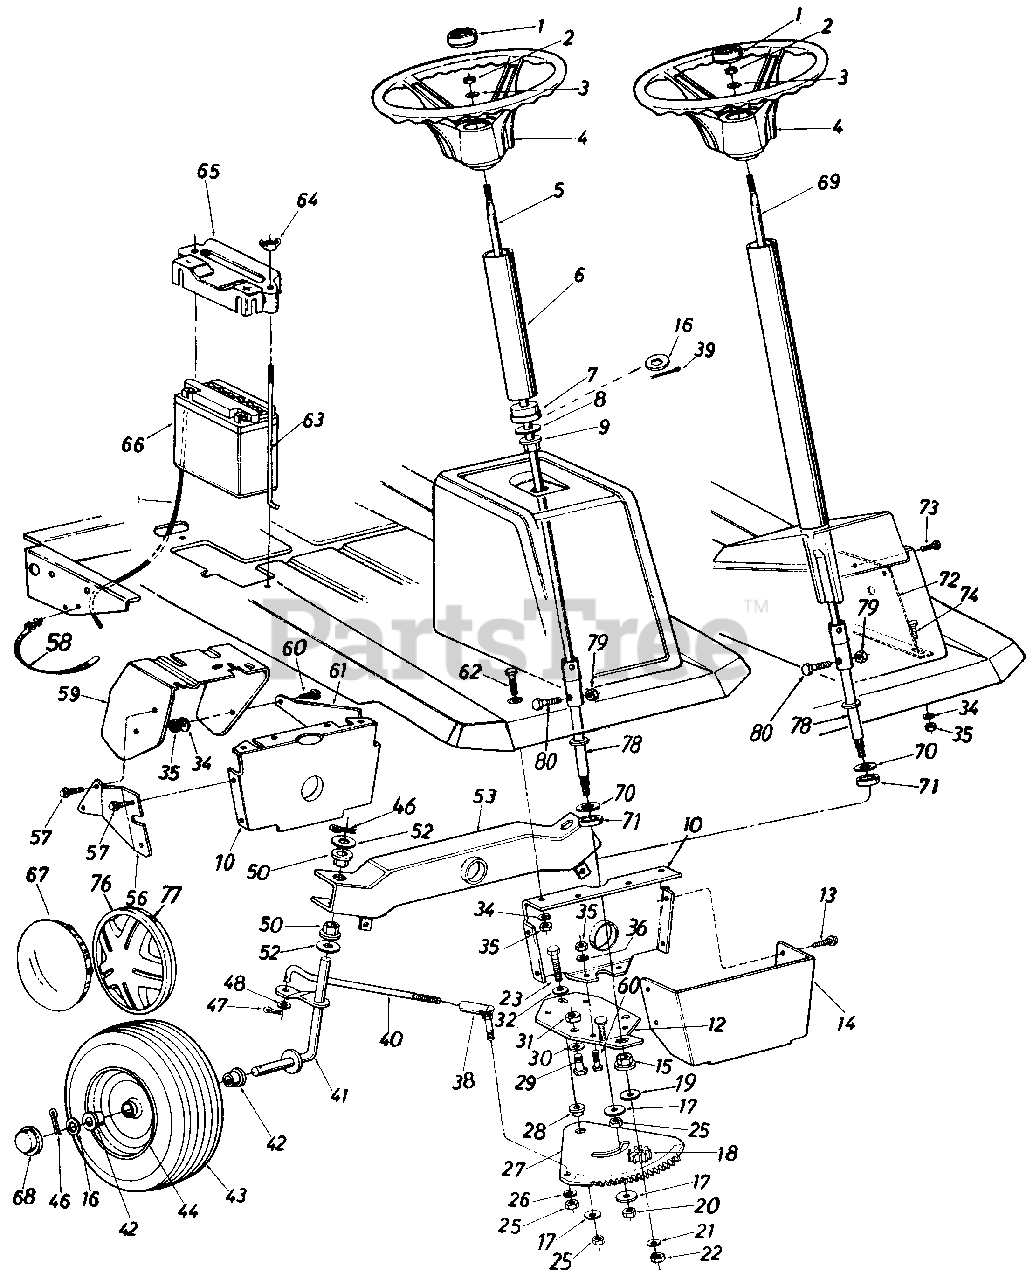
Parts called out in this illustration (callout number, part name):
1	Steering Wheel Cap
2	Hex L-Nut 5/16-24 Thd.
3	Bell-Wash. .345" I.D. x .88" O.D.
4	Steering Wheel Ass'y. (3 Spoke)
5	Steering Shaft Ass'y.
8	Fl-Wash. .635" I.D. x 1.24" O.D.
9	Hex Flange Bearing
13	Hex Wash. hd. AB-Tap Scr. 1/4 x .65" Lg.
16	Fl-Wash. .640" I.D. x 1.5" O.D.
17	Fl-Washer 3/8" I.D. x 1.37" O.D.
18	Steering Pinion Gear
19	Fl-Wash. .510" I.D. x 1" O.D.
20	Hex L-Nut 3/8-24
21	Fl-Wash. .34" I.D. x .68" O.D.
22	Hex Nut 5/16-24 Thd.
23	Hex Bolt 3/8-24 x 1.5" Lg. (Grade 5)
25	Hex Nut 3/8-24 Thd.
26	L-Wash. 3/8" I.D.
27	Steering Gear Segment
28	Shoulder Spacer .622" Dia. x .218
29	Hex Bolt (Nylon) 1/2-13 x .75"
30	Fl-Wash. .530" I.D. x .930"
31	Hex Nut 1/2-13 Thd.
32	Bell-Wash. .385" I.D. x .88"
34	L-Wash. 5/16" I.D.
35	Hex Nut 5/16-18 Thd.
36	Spr. Wash. .32" I.D. x .62" O.D.
38	Ball Joint Ass'y. 3/8-24 Thd.
39	Cotter Pin 1/8" Dia. x 1.00" Lg.
40	Steering Tie Rod
41	Front Axle Ass'y. - R.H.
42	Flange Bearing
44	Front Wheel Rim Only
47	Cotter Pin 1/8" Dia. x 1.00"
48	Fl-Wash. .385" I.D. x .87"
50	Hex Flange Bearing
52	Fl-Wash. .635" I.D. x 1.12"
53	Pivot Bar Ass'y.
58	Cable Tie
59	Clutch-Brake Pedal Ass'y.
60	Hex Bolt 5/16-18 x .75" Lg.
63	Battery Hold Down Rod
64	Wing Nut Solid 1/4-20 Thd.
65	Battery Hold Down Cover
66	12V Battery
67	Chrome Hub Cap
68	Plastic Hub Cap
69	Steering Shaft Ass'y.
70	Fl-Wash. .635" I.D. x 1.24" O.D.
71	Spacer (Plastic)
74	Hex Bolt 5/16-18 x 2.00" Lg.
76	Hub Cap - Beige
77	Spring Clip
78	Steering End Adapter
79	Hex Nylon L-Nut 1/4-20 Thd.
80	Hex Bolt 1/4-20 x 1.31" Lg.
